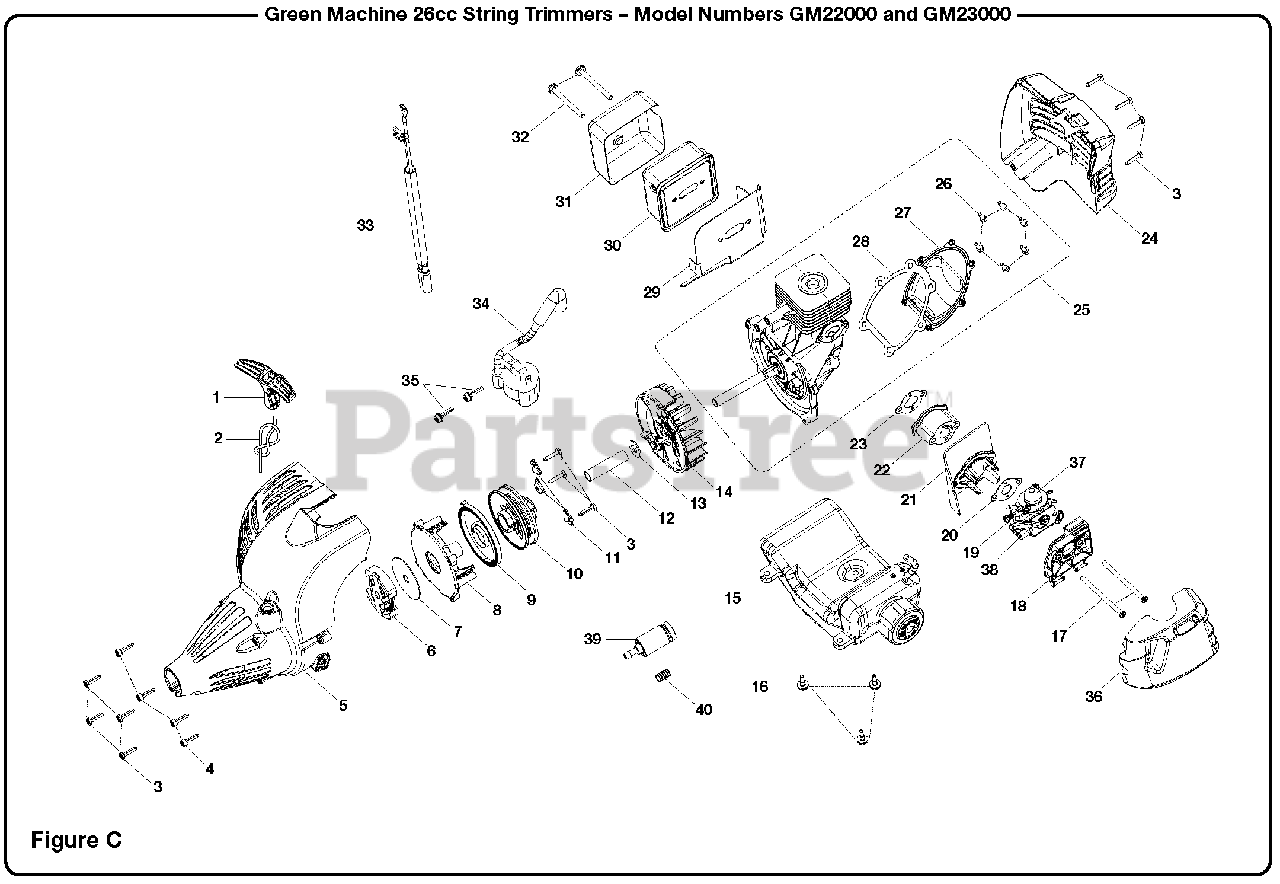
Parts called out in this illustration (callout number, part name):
1	Starter Grip
2	Starter Rope (42 in.)
3	Screw (M4 x 18 mm)
4	Screw (M4 x 16 mm)
5	Starter Housing Assembly
6	Clutch Assembly
8	Starter Baffle
9	Spring and Container
10	Easy Starter Assembly
11	Pulley Retainer
12	Spacer Tube
13	Washer
14	Flywheel Assembly
15	Fuel Tank and Cap Assembly (Inc. Key Nos. 39-40)
16	Screw (M4)
17	Bolt (M5 x 70 mm)
18	Air Box Base
19	Carburetor Assembly
20	Outer Heat Dam Gasket
21	Air Baffle
23	Inner Heat Dam Gasket
24	Rear Housing
25	Short Block Assembly (Inc. Key Nos. 26-28)
26	Screw (M4 x 12 mm)
27	Crankcase Cover
28	Crankcase Cover Gasket
29	Muffler Gasket
30	Muffler Assembly
31	Muffler Housing
32	Muffler Bolt (10-24 x 2-1/8 in.)
33	Electrical Lead Wire Assembly
34	Ignition Module
35	Screw (M4 x 19 mm)
36	Air Box Cover
37	Primer Bulb (Ruixing)
38	Choke Lever (Ruixing)
39	Fuel Filter
40	Compression Spring
